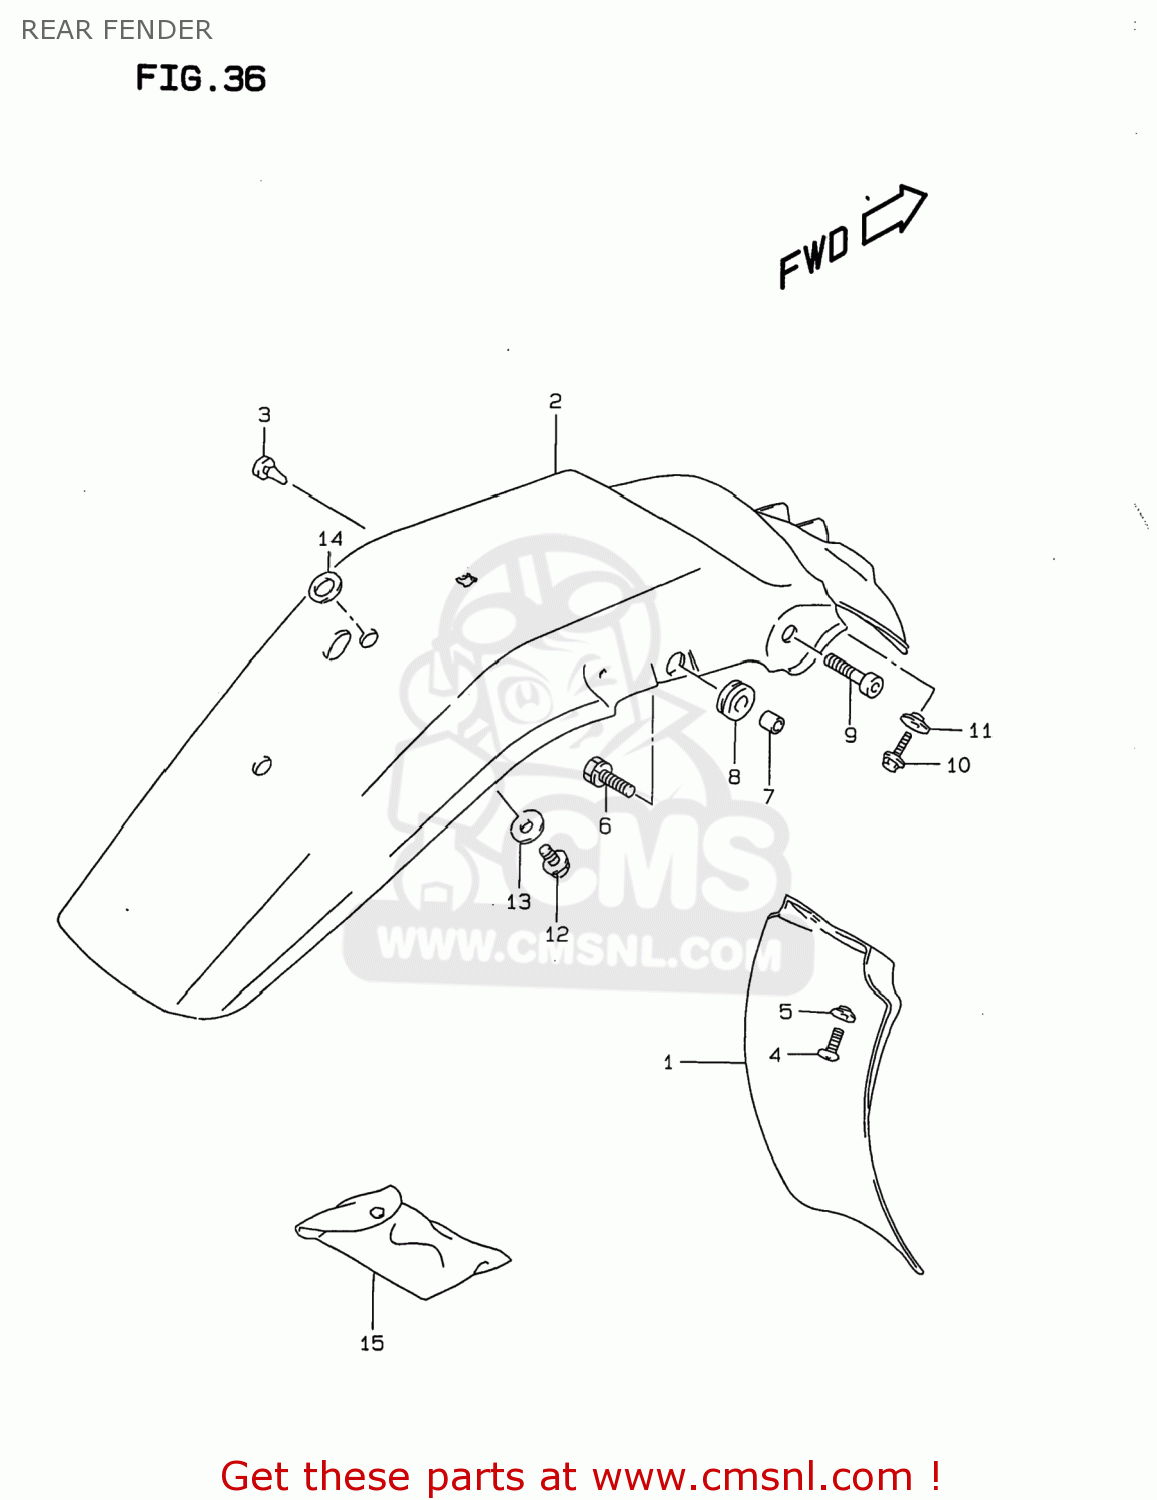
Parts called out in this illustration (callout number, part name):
1	BODY,RR FENDER FR
2	BODY,RR FENDER RR
3	CUSHION,RR FENDER SIDE
4	SCREW 6X12
5	WASHER
6	BOLT
7	SPACER(8.5X12X7)
8	CUSHION
9	BOLT(8X30)
10	BOLT
11	WASHER
12	BOLT, UPPER
13	WASHER
14	WASHER(14.2X26X1.2)
15	TOOL ASSY
